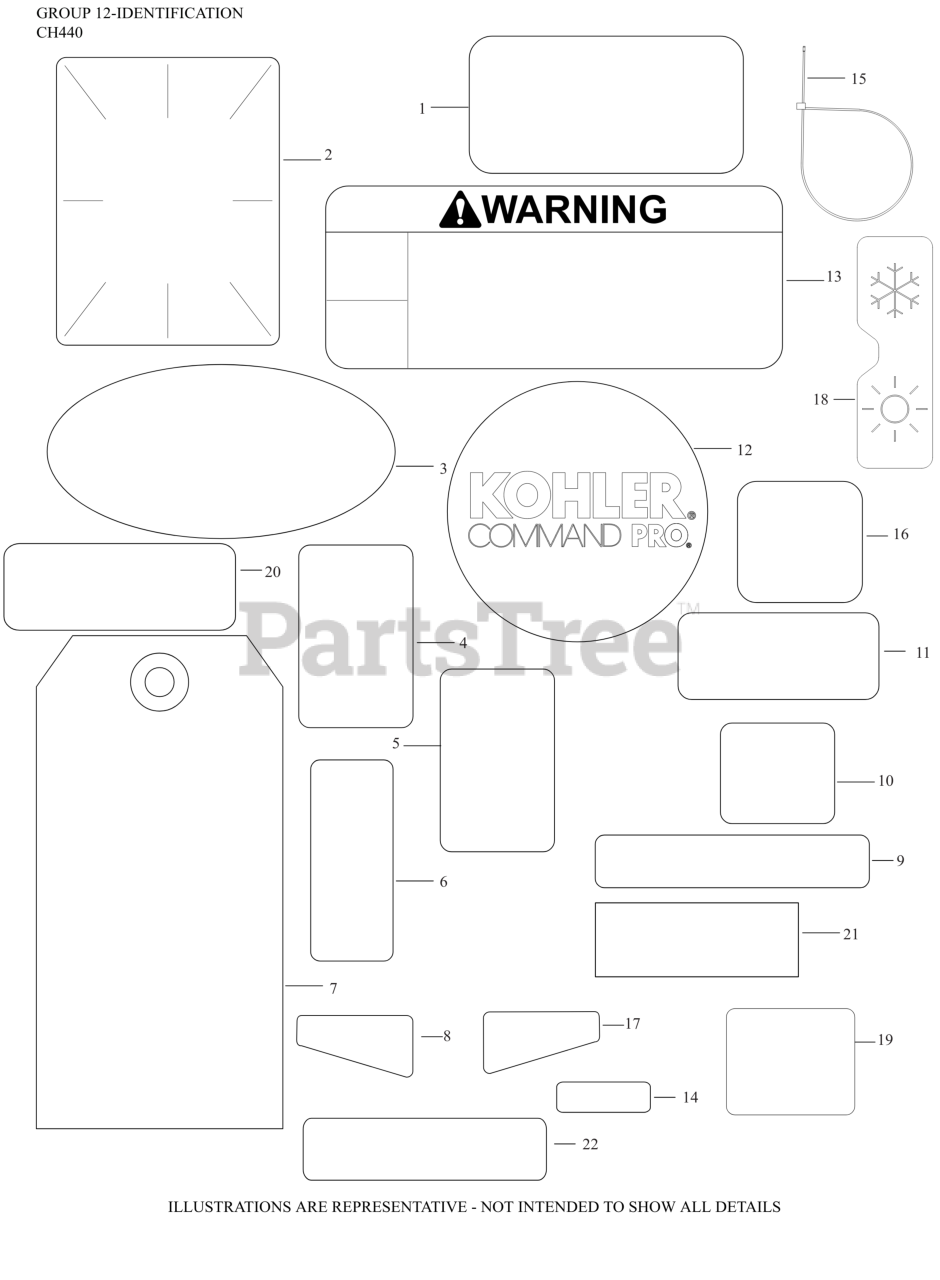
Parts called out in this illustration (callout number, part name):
1	LABEL, MAINTENANCE (CKY)
2	LABEL, CLEAR LAMINATION
3	DECAL, QUAD CLEAN SILVER
4	DECAL, SNOW FLAKE
5	DECAL, SUN
6	DECAL, FUEL/CHOKE - ON/OFF
7	TAG, HANG
8	DECAL, 14 HP/429cc/CH440
10	DECAL, BASE ARROW
11	LABEL, CANADIAN COMPLIANCE
11	DECAL, ETHANOL WARNING
12	LABEL, RECOIL 75MM
13	DECAL, WARNING
14	DECAL, ENGINE AND FUEL SHUT OFF
